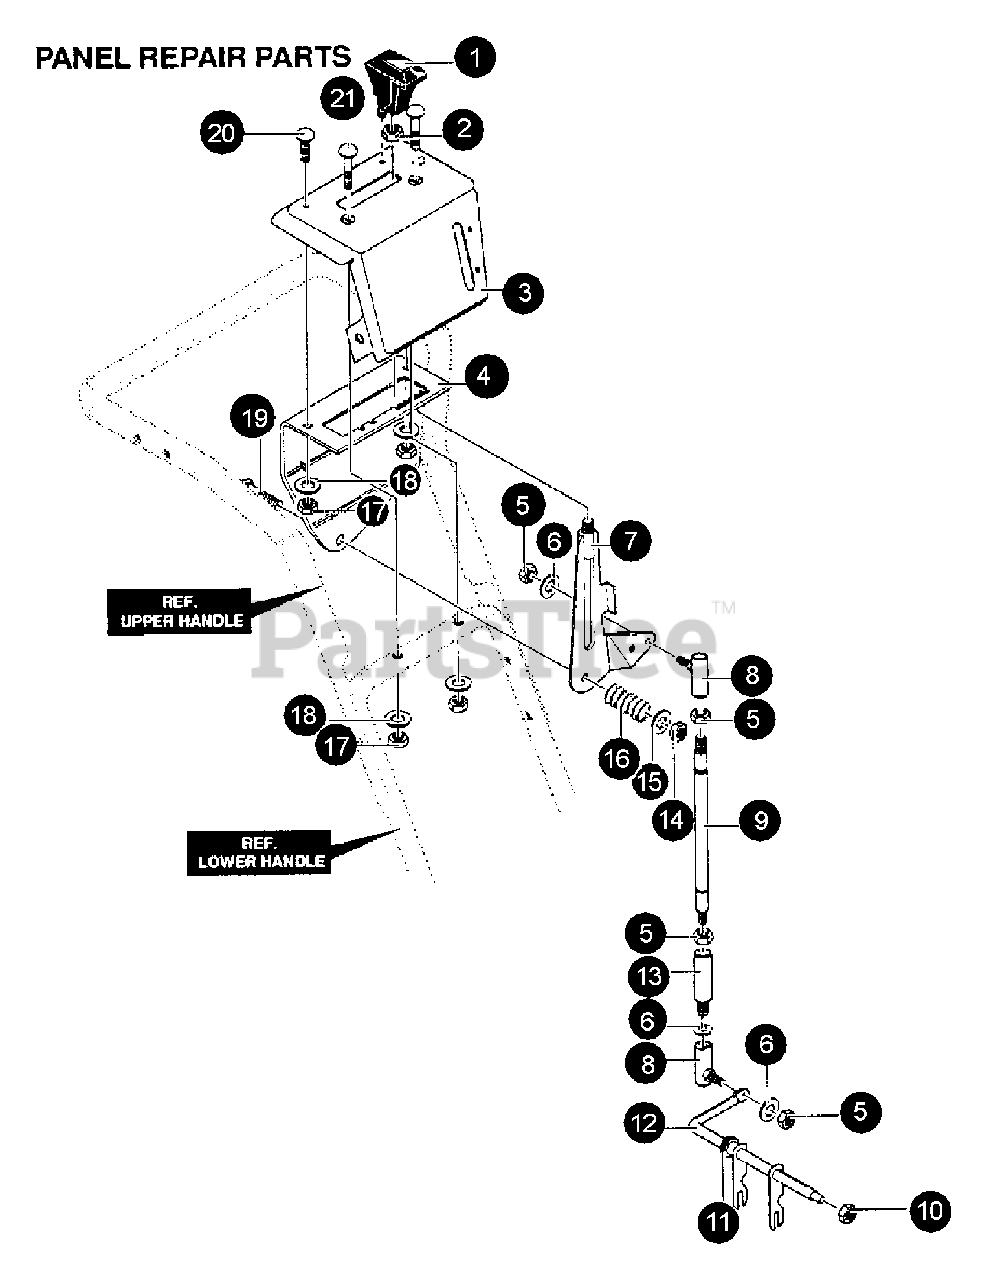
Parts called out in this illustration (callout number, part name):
1	KNOB, SHIFT
2	NUT, 3/8"-16
3	PANEL, CONTROL
4	BRACKET, SHIFT CONTROL
5	NUT, 5/16"-18
6	WASHER
7	SHIFT LEVER ASSY
8	JOINT, SHIFT BALL
9	ROD, SPEED CONTROL
10	NUT, 3/8"-16
11	BEARING, FL
12	YOKE ROD ASSY
13	ADAPTOR, ROD
14	NUT, 5/16 - 18
15	WASHER
16	SPRING
17	NUT - 1/4-20
18	WASHER, REGSPTLK0.263×0.49×0.07
19	SCREW - 5/16-18×1.75"
20	BOLT - 1/4-20×2.00"
21	BOLT - 1/4-20×0.63"
